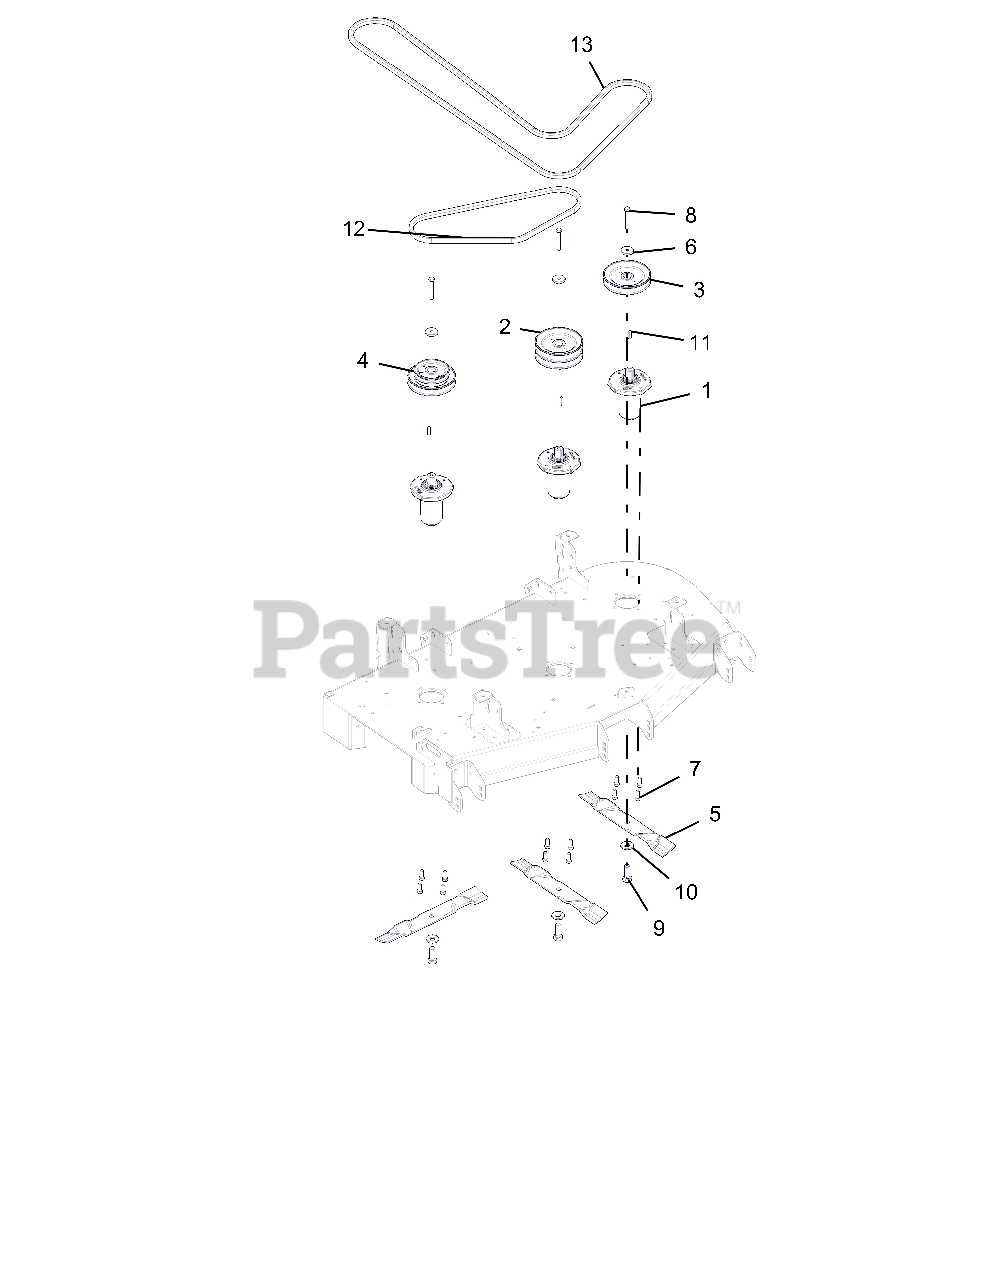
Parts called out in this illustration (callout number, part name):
1	SERVICE, ASM SPINDLE- DUCTILE
2	PULLEY, DOUBLE-1" ID X 5.75" OD-BLACK
3	PULLEY, V - 1" ID X 5.75" OD-BLACK
4	PULLEY, DOUBLE -1" ID X 5.75" & 4.25" OD
5	BLADE, 16.19" MOWER
6	RETAINER, SHEAVE SPINDLE
7	BLT-HEX .38-16X1.00 GR5 YWZC EP30
8	BLT-HEX .38-16X2.75 GR8 YWZC
9	BLT, HEX .62-18X1.75 GR8 YWZC
10	WSHR, BLVL .63X1.625X.14
11	KEY-SQ .250X.250X1.00 RC 40-50
12	V-BELT, B-RAW EDGE COGGED
13	BELT, BB 118.00 WRAPPED HEX
